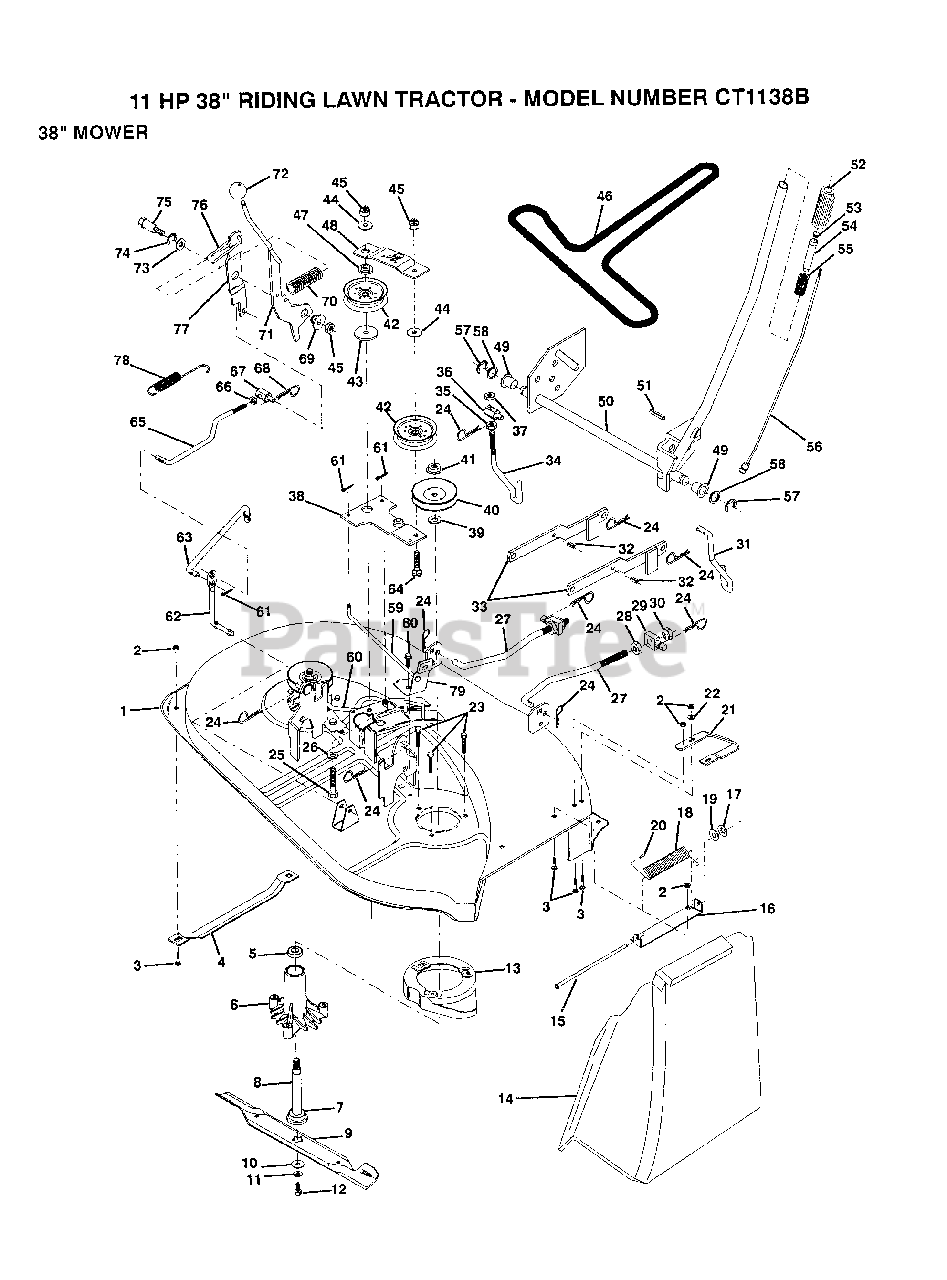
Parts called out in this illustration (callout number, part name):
3	BOLT
4	RUNNER-LH M
5	BEARING
6	HSG ASM MANDREL
7	BEARING.BALL
10	WASHER BLADE
12	BLADE BOLT
14	DEFLECTOR-SHLD T
15	ROD-HINGE T
17	NUT PUSH M
19	WASHER
20	CAP-SLEEVE LT
21	RUNNER RH
22	WASHER M
25	BOLT
26	WASHER GT
27	LINK.FRONT
28	NUT
29	TRUNION
30	NUT.LK.W/WSH.1/2.
31	LINK LIFT RH
32	SPRING PIN
33	SUSP ARM REAR
34	LIFT LINK LH
35	NUT
38	IDLER ARM ASSY
39	WASHER
42	FLAT IDLER PULLEY
43	SPACER RETAINER
44	WASHER GT
46	BELT-V.88.12.MW
47	RETAINER SPACER
48	IDLER ARM STIFF
49	NYLON BEARING
51	PIN-GROOVE LT
52	GRIP
58	WASHER
59	BRAKE ROD RH
60	BRAKE ROD LH
62	PIVOT ROD
63	CLUTCH ROD SECOND
64	BOLT
66	NUT
67	TRUNION
68	RETAINER M
69	BUSHING
71	CLUTCH ARM PRI AS
72	KNOB T(3/8 HOLE)
73	WASHER
74	RING
75	SHOULDER BOLT
76	SPRING KEEPER
77	CLUTCH ARM SECOND
78	RETURN SPRING
79	BRAKE ASM
80	SCREW
